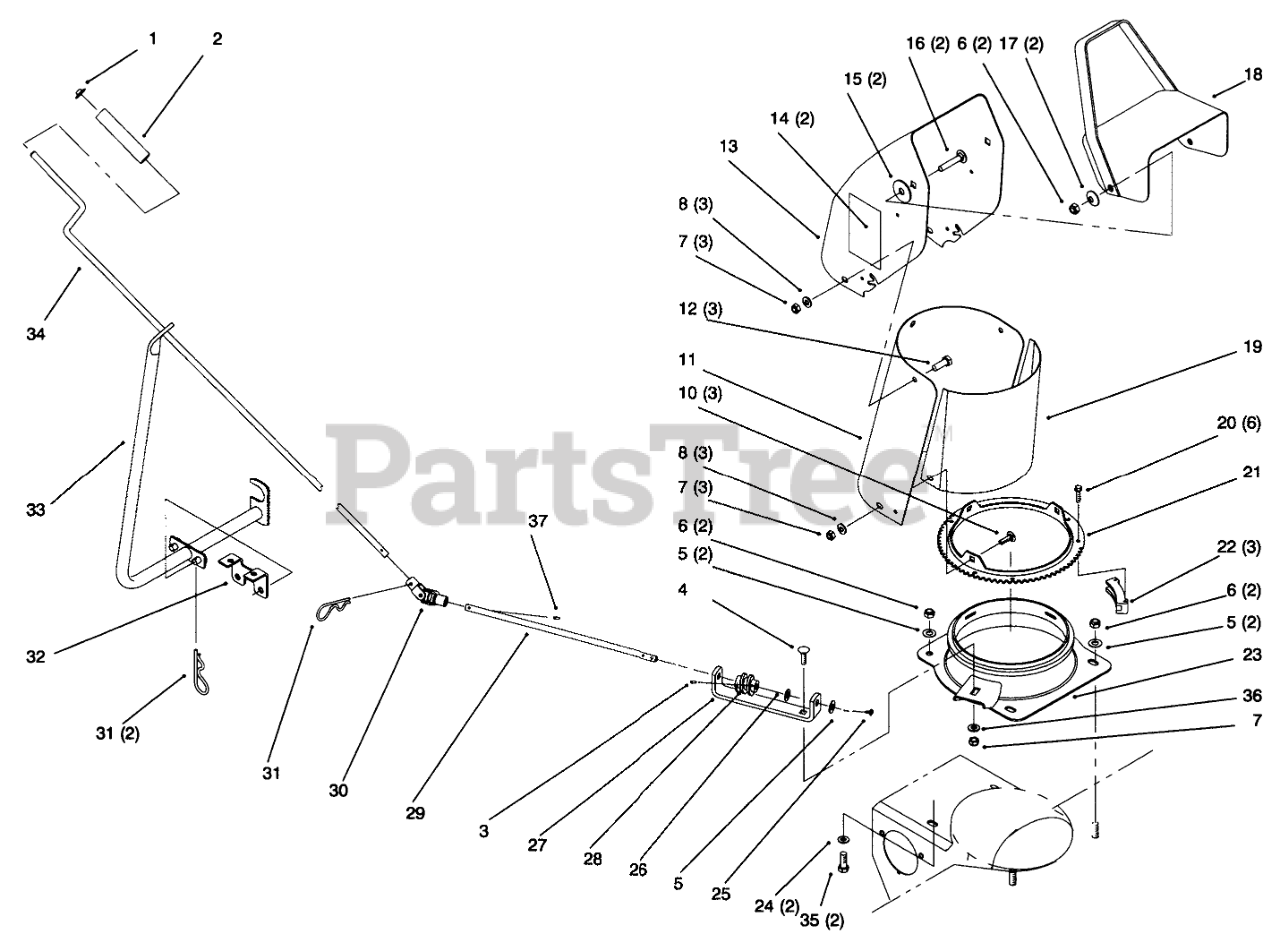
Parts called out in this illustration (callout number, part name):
1	RETAINER-PUSH ON
2	GRIP-CONTROL, CHUTE
3	PIN-SPRING
4	BOLT-CARR
5	WASHER-FLAT
6	NUT-LOCK, NI
7	NUT-LOCK, NI
8	WASHER-PLAIN
10	BOLT-CARR
11	EXTENDER-CHUTE, UPPER
12	SCREW-HH
13	CHUTE
14	DECAL-DISCHARGE DANGER
15	WASHER-RUBBER
16	BOLT-CARR
17	WASHER-BELLEVILLE
18	DEFLECTOR
19	SHIELD-DEFLECTOR
20	SCREW-SPECIAL
21	CHUTE SWIVEL RING
22	RETAINER-CHUTE
23	ADAPTER
24	WASHER-SPACER
25	PIN-COTTER
26	WASHER-SPRING
27	BRACKET-WORM
28	GEAR-WORM, CHUTE
30	JOINT-UNIVERSAL
31	PIN-HAIR
32	BRACKET
33	SUPPORT
34	ROD-CHUTE CONTROL
35	SCREW-HH
36	WASHER-LOCK
37	PIN-SPRING
